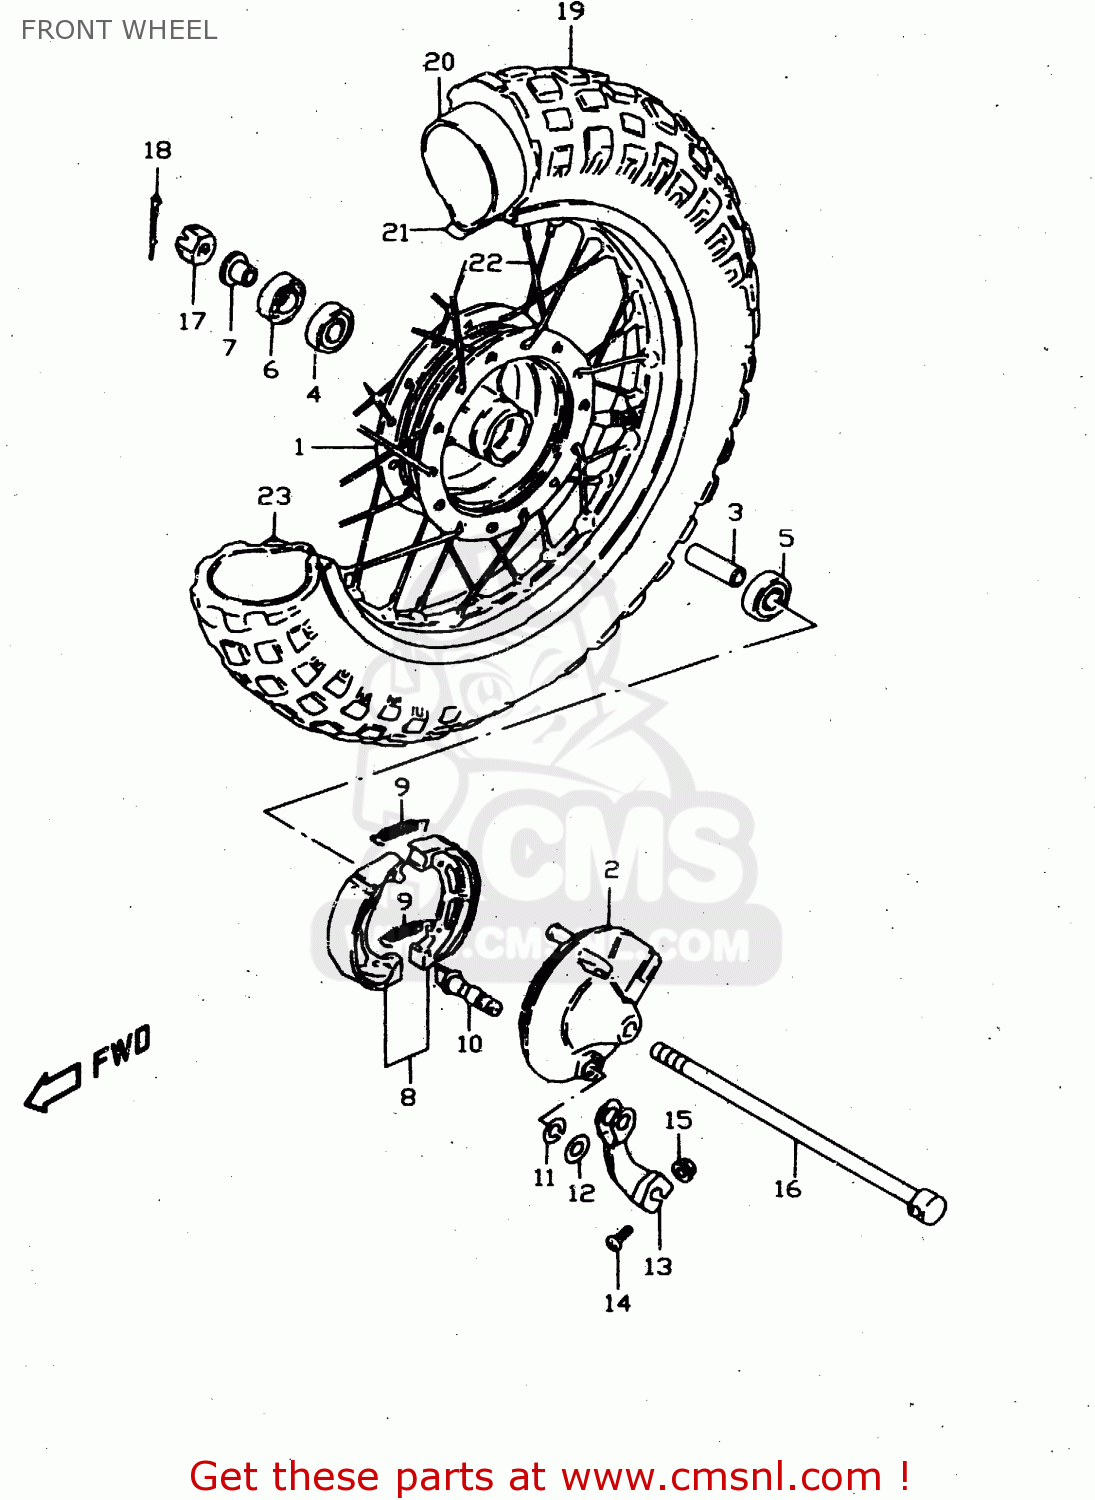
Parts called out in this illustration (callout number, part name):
1	HUB,FR WHEEL
2	PANEL,FR BRAKE ANCHOR
3	SPACER(10.2X16X47)
4	BEARING(10X26X8)
5	BEARING
6	SEAL,OIL(15X27X6)
7	SPACER,AXLE
8	SHOE & SPRING SET (NAS)
9	SPRING(L:35.8)
10	CAM,BRAKE
11	O RING(D:2.4,ID:9.6)
12	WASHER(10.5X18X1)
13	LEVER,FR BRAKE CAM
14	BOLT
15	NUT
16	AXLE,RR
17	NUT
18	PIN 20X20
19	TIRE
20	TUBE,INNER
21	PROTECTOR,INNER TUBE
22	SPOKE SET,RR
23	RIM,WHEEL
